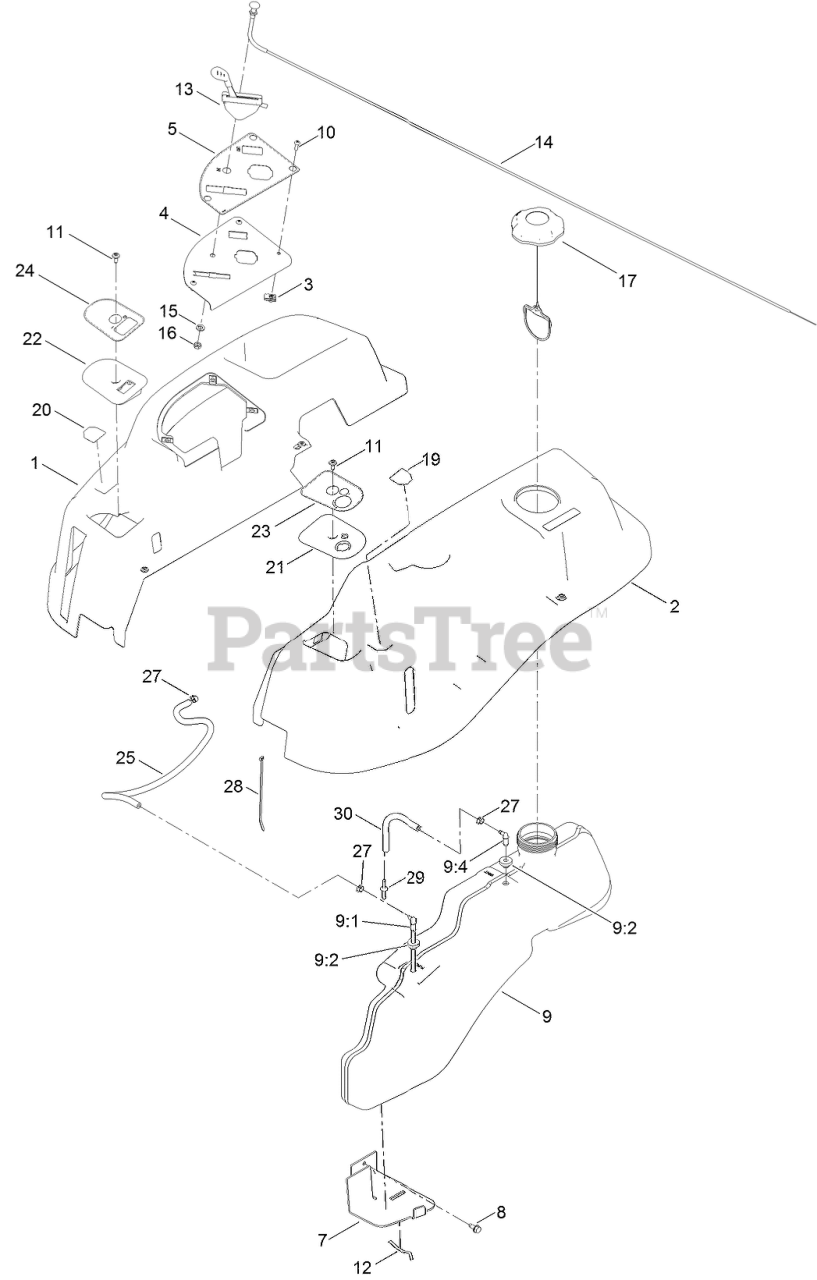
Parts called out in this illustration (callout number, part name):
1	POD-RH
2	POD-LH
4	PLATE-CONTROL
5	DECAL-PANEL, CONTROL
7	SUPPORT-TANK, FRONT
8	SCREW-HWHTF
9	FUEL TANK ASM
9:1	CONNECTOR-ELBOW, 90 DEG
9:2	BUSHING
9:4	FITTING-PLASTIC
10	SCREW-PRH
11	SCREW-SHOULDER
12	SPRING
13	CABLE-THROTTLE
14	CABLE-CHOKE
15	WASHER-LOCK
16	NUT-HJ
17	CAP-FUEL, RATCHETING
19	DECAL-NMIR
20	DECAL-CONTROL, PEDAL
21	COVER-LH
22	COVER-RH
23	DECAL-KEYCHOICE
24	DECAL-BRAKE, PARKING
25	HOSE-FUEL
27	CLAMP-HOSE
29	ADAPTOR-ORIFICE
30	HOSE-FUEL
